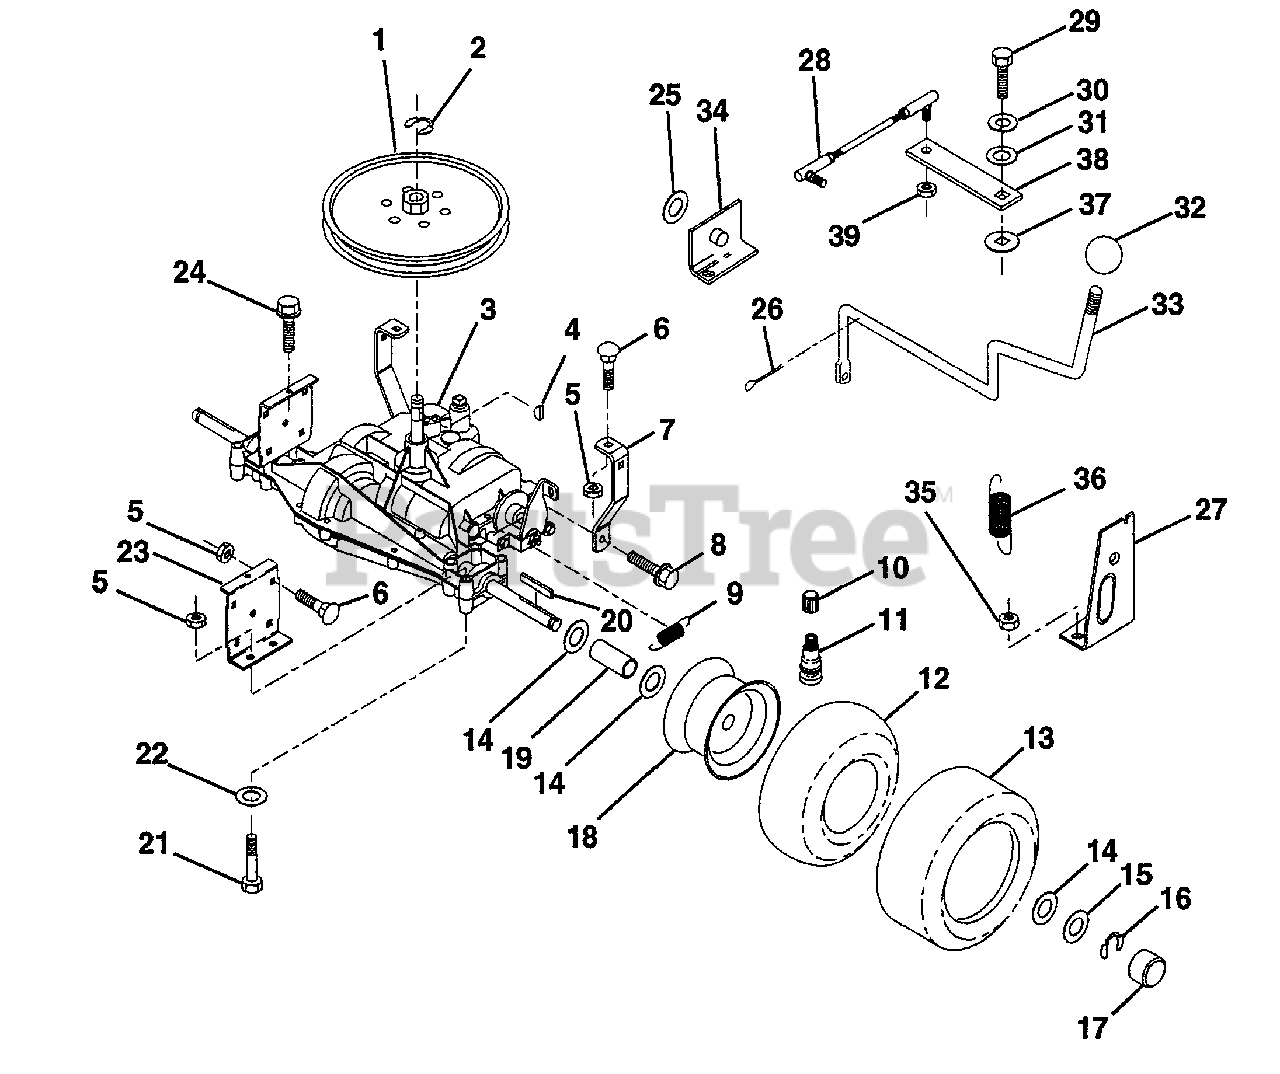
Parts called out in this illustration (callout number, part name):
2	Ring, Retainer
3	Transaxle, Peerless 4 speed Model No. 930-026
4	Key, Woodruff #9
5	Nut, Crownlock 5/16-18
6	Bolt, Carriage 5/16-18 UNC x 3/4
7	Strap, Torque
8	Screw, Hex Thdrol 5/16-18 x 1/2
9	Spring, Brake
10	Cap, Valve
11	Stem, Valve
13	Tire, Rear
14	Washer 25/32 x 1-1/4 x 16 Ga.
15	Washer 35/32 x 1-5/8
20	Key, Square
21	Bolt, Fin Hex 5/16-18 x 2-1/2
22	Washer 11/32 x 11/16 x 16 Ga.
23	Bracket, Transaxle
24	Screw 5/16-18 x 3/4
25	Washer 17/32 x 1 x 16 Ga.
26	Pin, Cotter 1/8 x 1
27	Support, Handle Shift R. H.
28	Link, Shift
29	Bolt, Fin Hex 1/4-28 UNF x 3/4 Gr. 8
30	Washer, Lock 1/4
31	Washer 9/32 x 3/4 x 10 Ga.
32	Knob, Shift Control
34	Support, Handle Shift L. H.
35	Nut, Keps 5/16-18
36	Extension, Spring
37	Washer, Shift Plate
38	Arm, Shift
39	Nut, Hex Nylon
